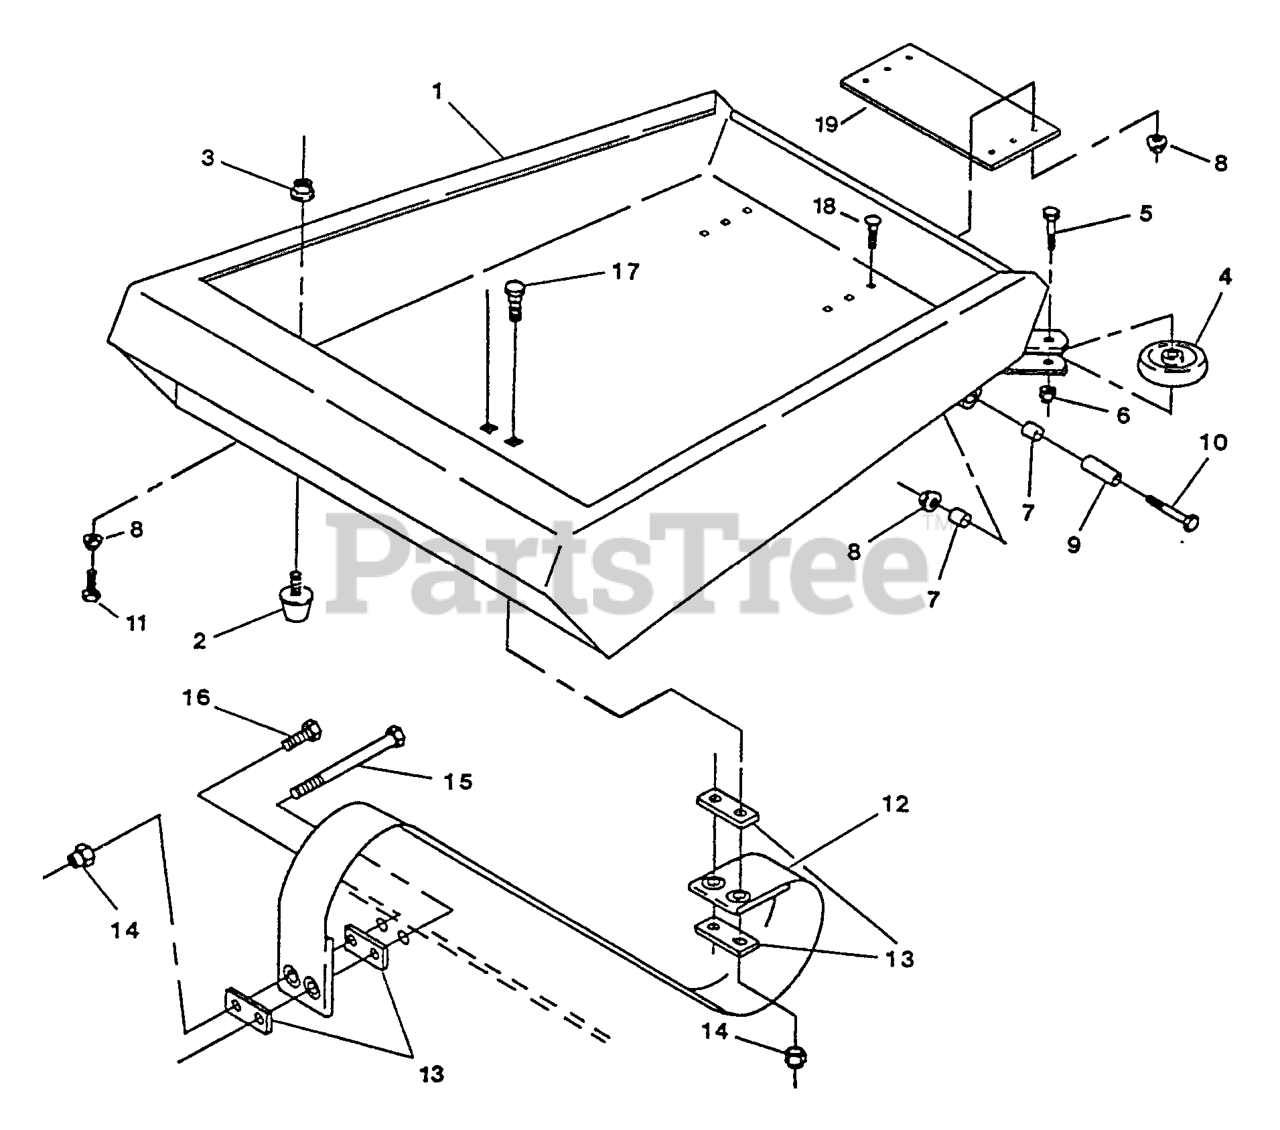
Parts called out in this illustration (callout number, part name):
2	BUMPER-RUBBER
4	WHEEL,RUBBER
7	SLEEVE-BEARING
9	BUSHING,BOX PIVOT
12	STRAP,BOX RESTRAINT
13	CLAMP,STRAP
17	Bolt, Carriage 1/4-20 X 1
19	WEIGHT,DUMP BOX PNTD
